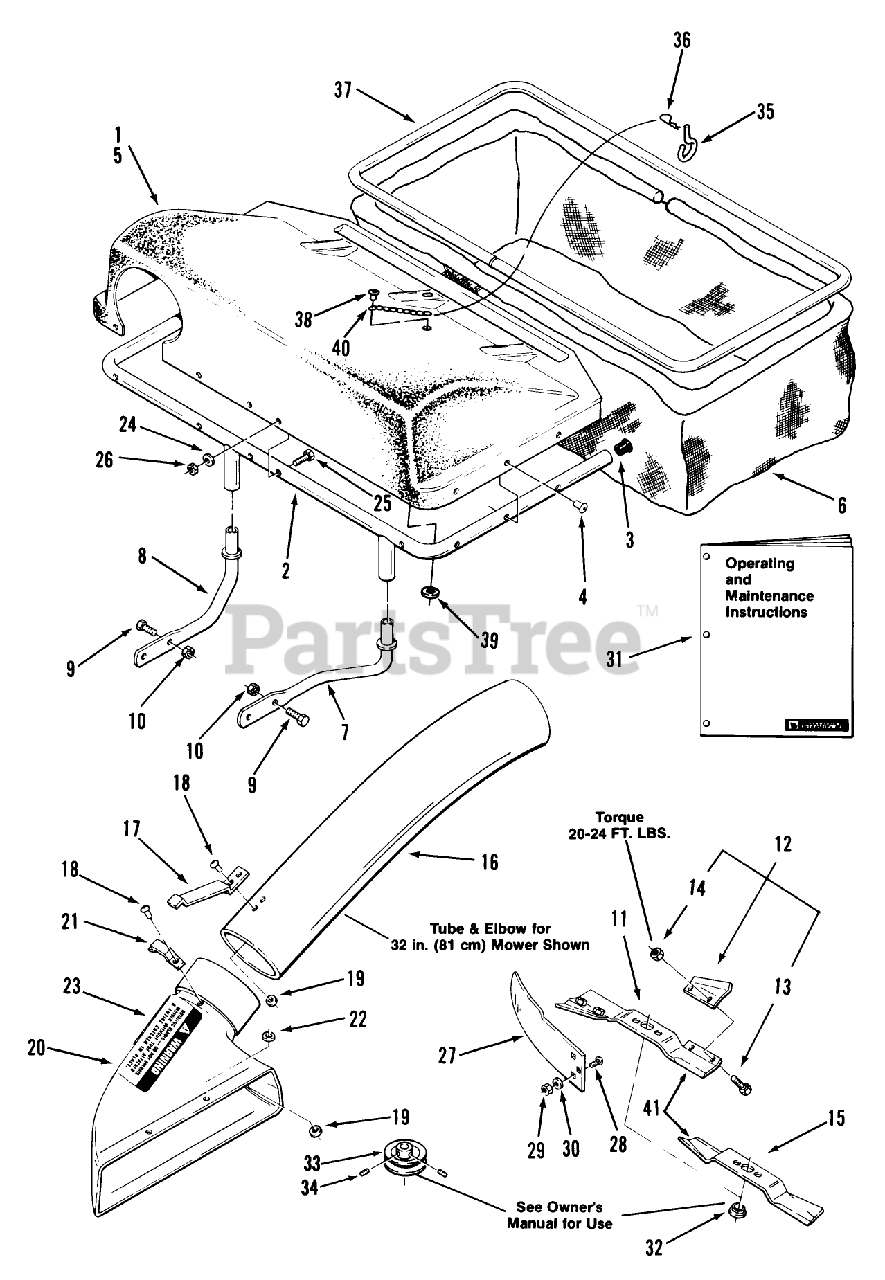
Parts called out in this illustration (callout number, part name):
4	Poprivet 3/16 dia. x .575
8	ROD QUICK ATTACH *B
11	ASSY-HI LIFT BLADE
12	S/A 37 LIFT TAB KIT
13	BOLT 5/16-18X5/8
14	NUT-HEX
15	BLADE 16.50
16	CHUTE 37" BAGGER
21	BRACKET
27	BAFFLE-DEFLECTOR *B
31	Operating and Maintenance Instructions
32	SPACER BLADE
33	PULLEY-SPLIT
36	Hairpin Cotter
37	FRAME-BAG *B
38	RIVET
41	KIT-BLADE (SERVICE)
